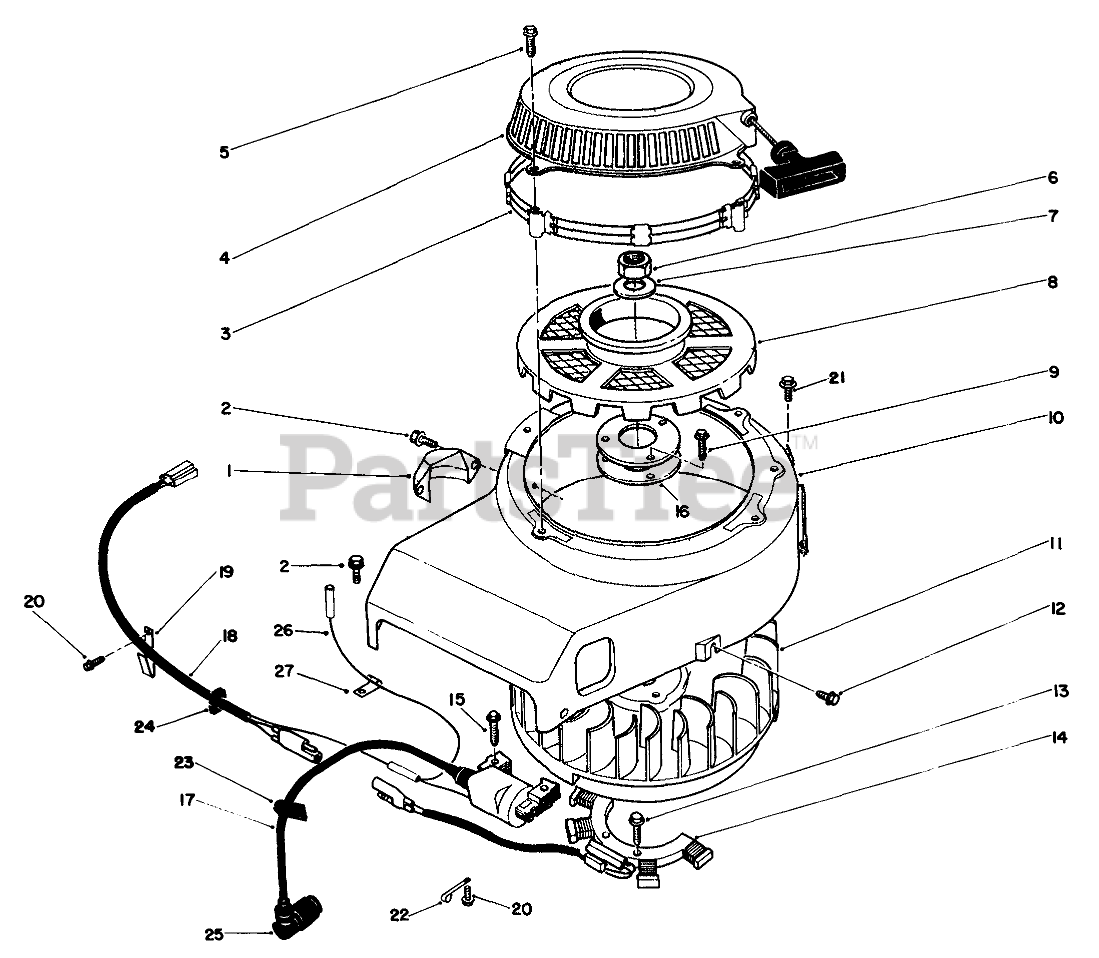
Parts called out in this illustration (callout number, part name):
4	Recoil Starter Assembly
5	BOLT-FLANGED (6X10)
9	Bolt-Flanged (8X12)
10	Housing-Fan
11	Flywheel
12	BOLT-FLANGED (6X10)
15	Bolt
17	Coil
20	Bolt-Flanged (6X10)
21	Bolt-Flanged (6X14)
25	Cap-Spark
26	Lead Wire
27	Clamp
